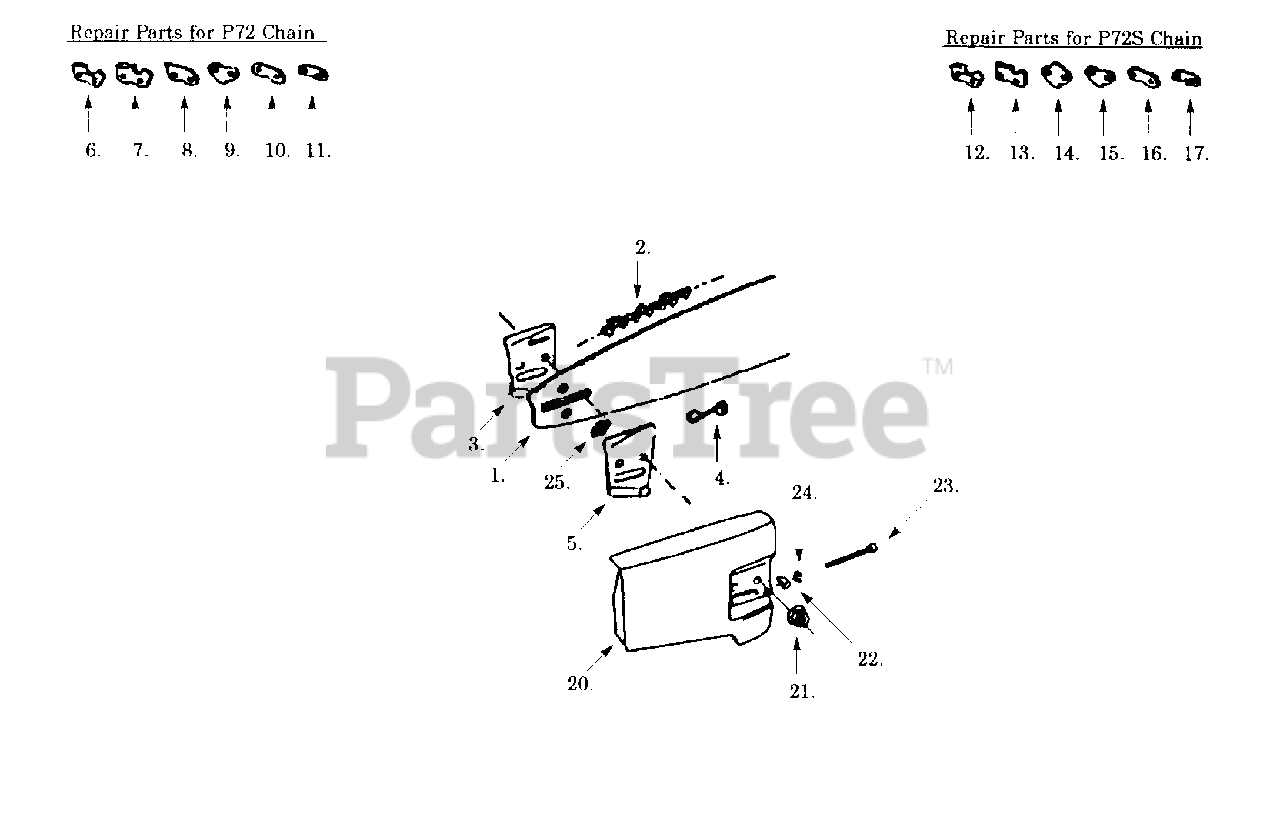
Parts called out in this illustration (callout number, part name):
1	16", 3/8 P, .050 G
1	18", 3/8 P, .050 G
1	20", 3/8 P, .050 G
1	24", 3/8 P, .050 G
1	28", 3/8 P, .050 G
1	Sprocket Nose Bar
1	16", 3/8 P, .058 G
1	18", 3/8 P, .058 G
1	20", 3/8 P, .058 G
1	24", 3/8 P, .058 G
1	Hard Tip Bar
2	16"/60-P720
2	18"/66-P720
2	20"/70-P720
2	21"/72-P720
2	24"/81-P720
2	28"/90-P720
2	16"/60-P730
2	20"/72-P730
2	24"/84-P730
2	13"/84-P730-Bow
3	Guide Bar Plate Inner
5	Guide Bar Plate Outer
6	R.H. Cutter
7	L.H. Cutter
8	Guard Drive Link
9	Drive Link
10	Tie Strap
11	Pre-Set Tie Strap
12	R.H. Cutter
13	L.H. Cutter
14	Guard Drive Link
15	Drive Link
16	Tie Strap
17	Pre-Set Tie Strap
20	Bar Clamp Ass'y.-Model 375
21	Nut
22	Bar Adjusting Pin
